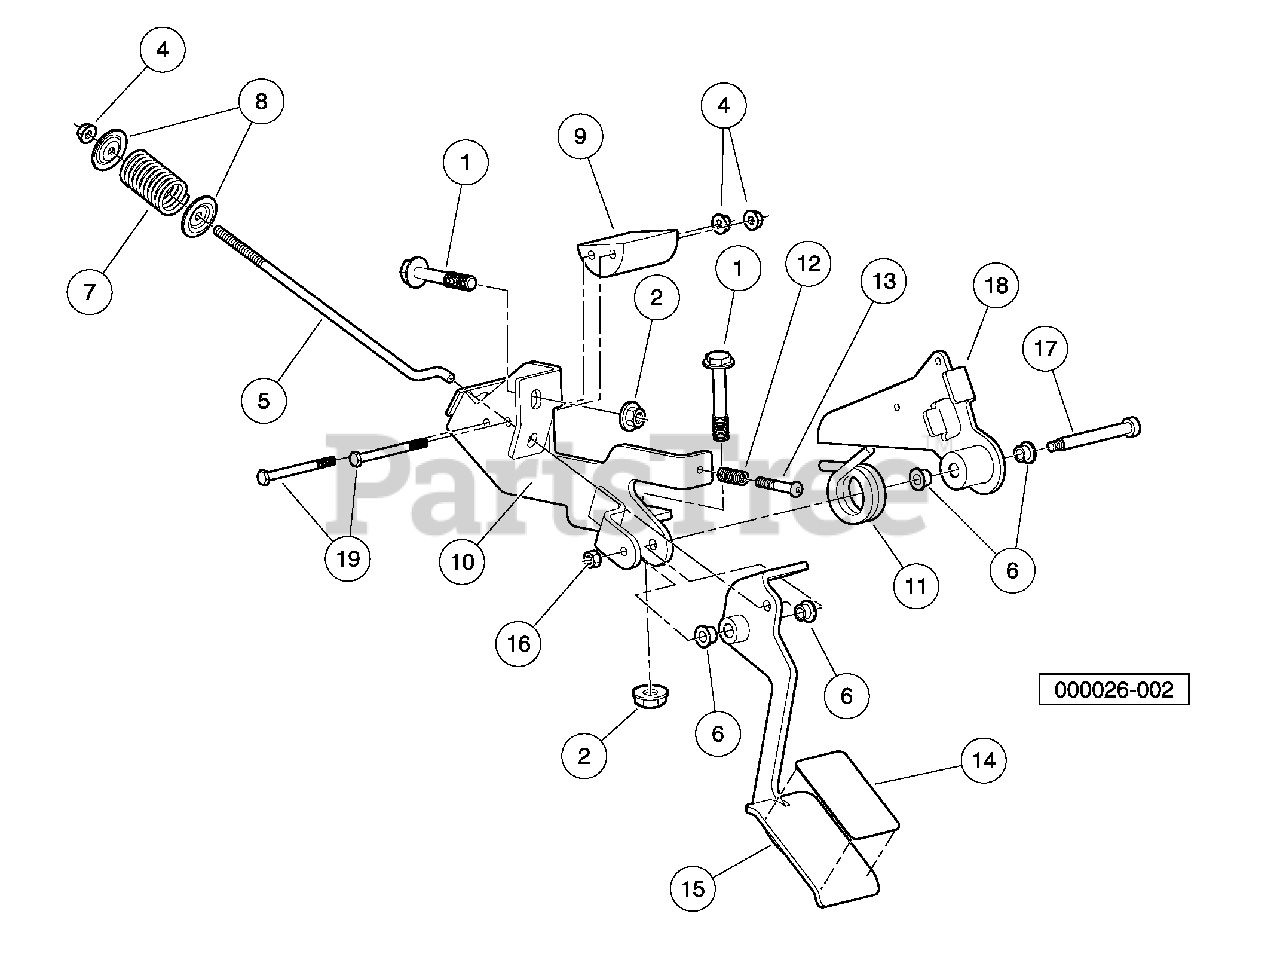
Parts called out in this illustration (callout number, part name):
1	Bolt Flanged Head, M8 X 1.25 X 65
2	Lock Nut, Flg M8 X 1.25 Nylon
3	Asm, Accelerator Pedal
4	Nut-m6x1.0 Flng All Mtl Lock
5	Pullrod, Spring, Compression
6	Bushing, Greaseless
7	Spring, Comp, Pedal, Pullrod
9	Guide, Cable, Accelerator
10	Weldment, Bracket, Pedal
11	Spring, Torsion
12	Spring, Stop, Pedal
13	Bolt, Stop, Pedal
14	Pad, Grip Tape, Accelerator
15	Weldment, Pedal, Accelerator
16	Nut M6x1 Mech Def Center
17	Bolt, Shoulder, M8 X 70, Hc
18	Weldment, Lever, Lost Motion
19	Bolt, M6 X 1 X 70
